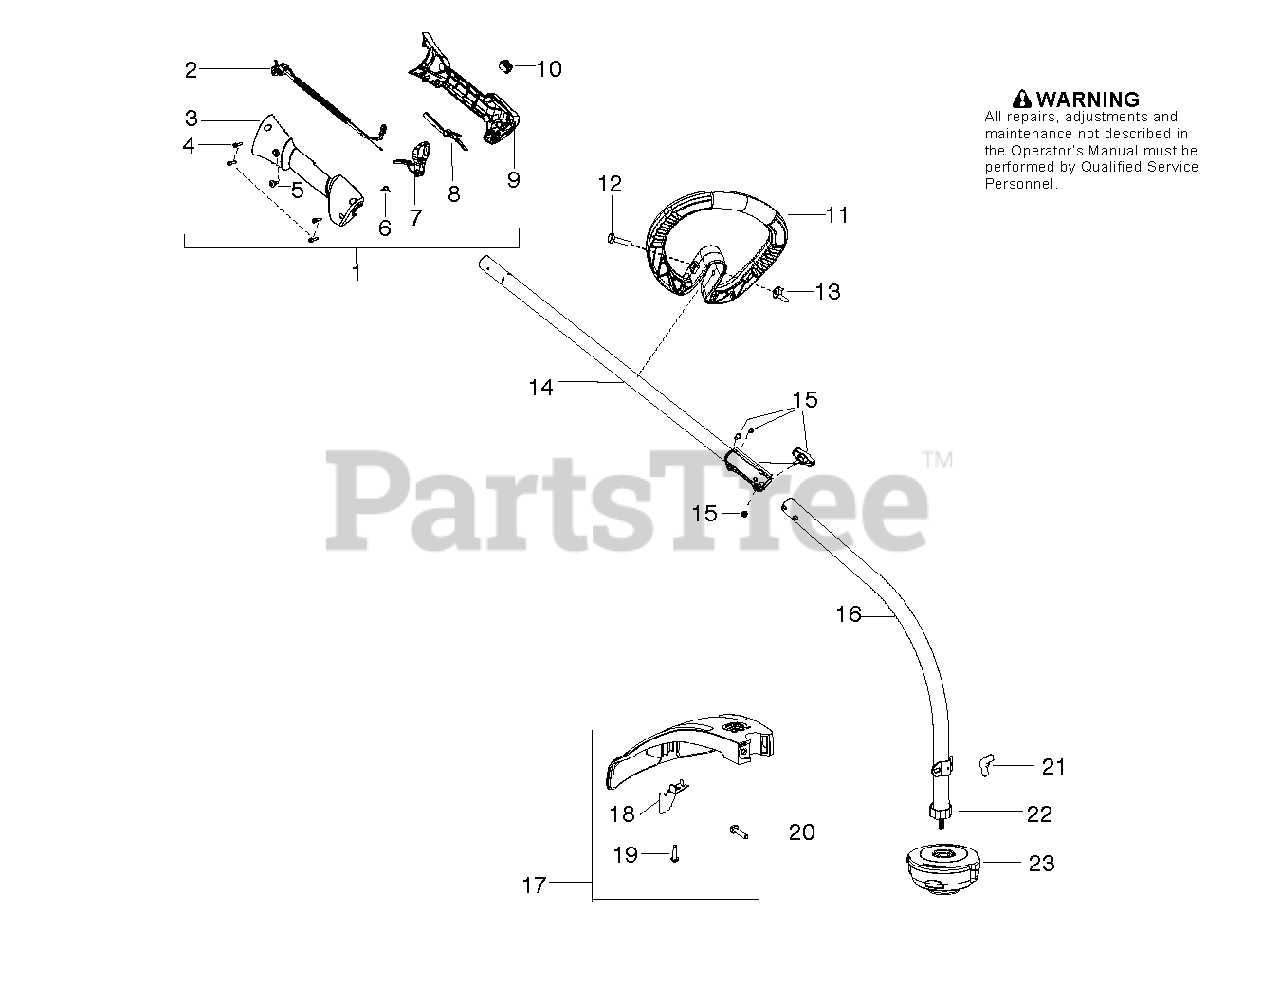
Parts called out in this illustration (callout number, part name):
2	ASSY CABLE/WIRE HARNESS
3	HANDLE HALF RIGHT
4	SCREW M4 X 1.75 PT 16MM
5	SCREW M4 X 1.75 PT 16MM
8	LOCKOUT TRIGGER
9	HANDLE HALF LEFT
10	STOP SWITCH
11	HANDLE ASSIST 1"
12	BOLT, TYPE 2
13	WINGNUT, TYPE 2
14	Drive Shaft Kit, Upper
15	ASSY COUPLER BLACK
16	KIT DRIVE SHAFT LOWER CD
17	Shield Kit
18	LINE LIMITER
20	BOLT, TYPE 2
21	WINGNUT, TYPE 2
22	DUST CUP
23	Trimmer Head Assembly, Tng P25 Pp28 Clockwise
